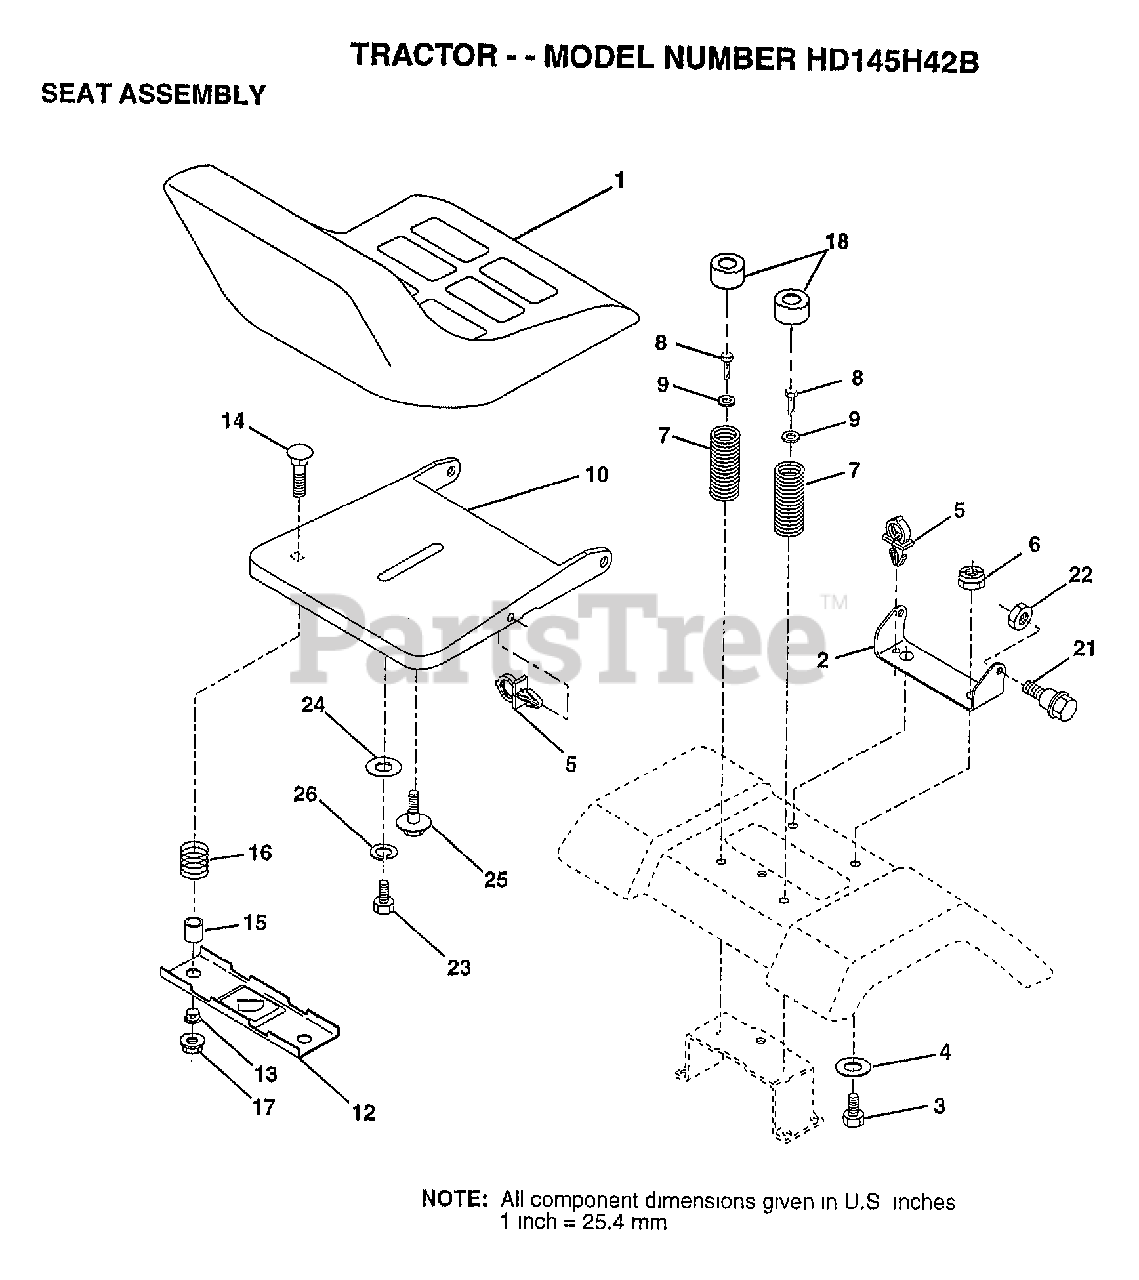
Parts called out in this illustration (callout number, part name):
1	SEAT
2	BRACKET PVT SEAT
3	BOLT
4	WASHER PM
5	CLIP.PUSH-IN.HING
6	NUT
7	SPRING COMPRESSIO
8	SCREW GTV
9	WASHER
10	PAN-SEAT
12	BRKT SWITCH
13	BUSHING
15	SPLIT SPACER
16	SPRING
18	CAP SPRING
21	"BOLT,SHOULDER"
23	BOLT
24	WASHER
25	"BOLT,SHOULDER"
26	LOCKWASHER
